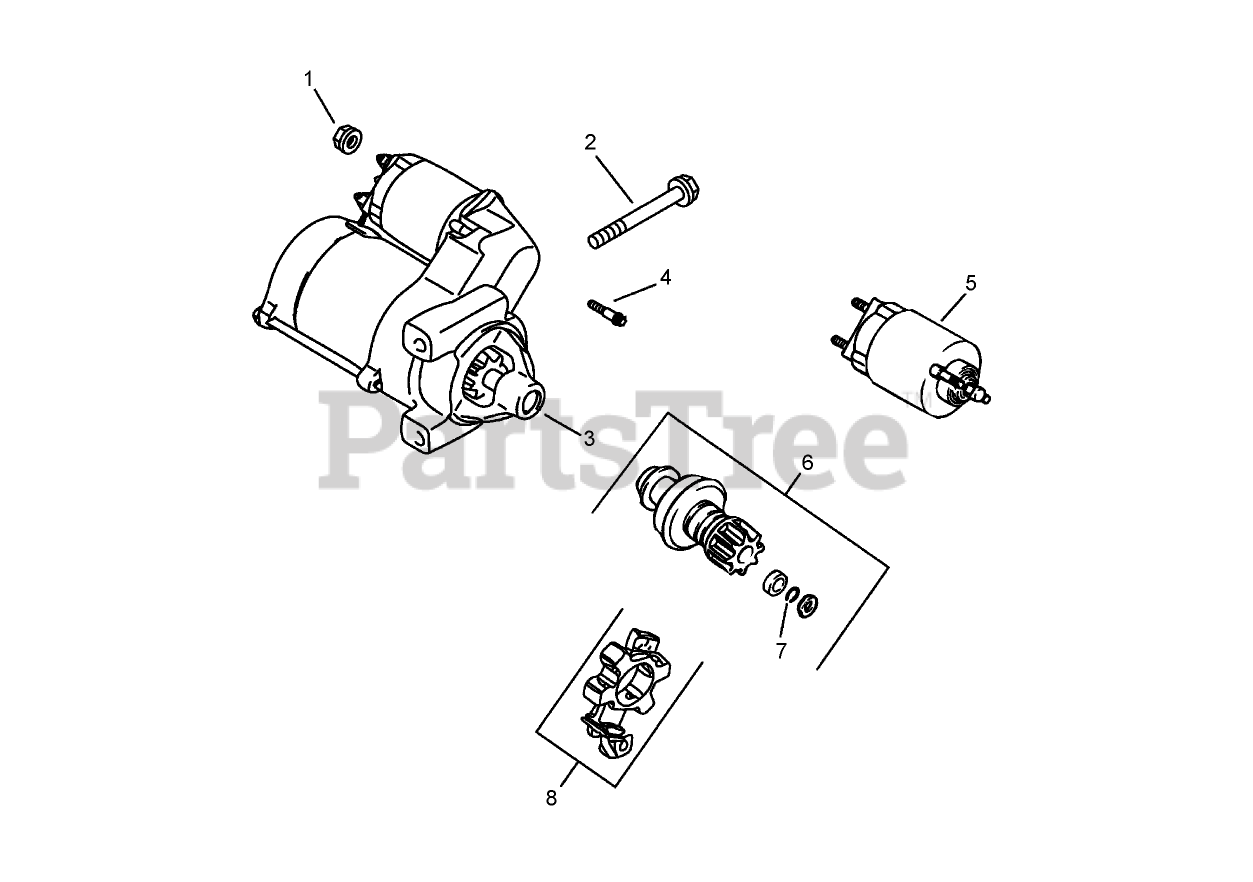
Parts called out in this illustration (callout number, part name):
1	NUT-FLANGE (M8X1.25)
2	SCREW-FLG (M8X1.25X80)
3	Starter ASM (Includes 4-8)
4	SCREW-TORX HEAD, EXTERNAL
5	Solenoid Kit (Includes 4)
6	Pinion Drive Kit (Includes 7)
7	RING-RETAINING
8	BRUSH HOLDER KIT
